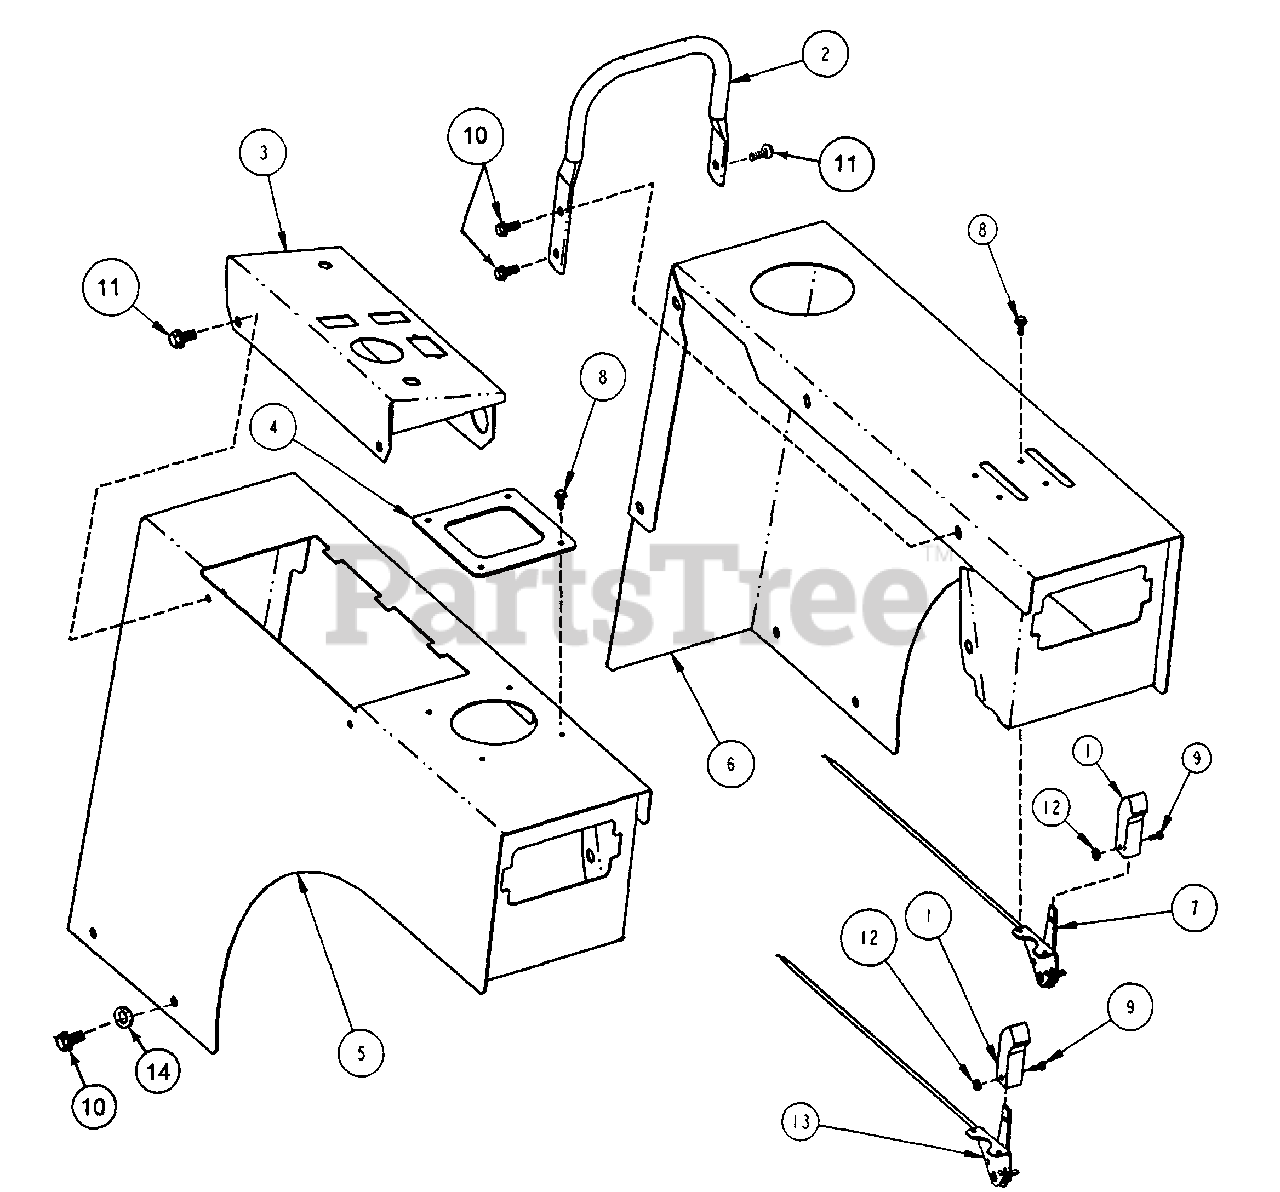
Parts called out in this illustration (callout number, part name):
1	LEVER, Throttle Control
2	HANDLE, 5/8" Tubing
3	PANEL, Console
4	PLATE, Joystick Control
5	FENDER, R.H.
6	FENDER, L.H.
7	CABLE, Choke, Kohler
8	SCREW, #10-24 x 1/2" Hex Washer Self-Tap (Torx)
9	SCREW, #8-32 x 3/8" Machine
10	SCREW, 5/16-18 x 5/8" Hex Washer Face Self-tap
11	SCREW, 1/4-20 x 5/8" Hex Flange Lock
12	NUT, #8-32 Hex
13	CABLE, Throttle, Kohler
14	WASHER, 5/16 I.D. Flat
